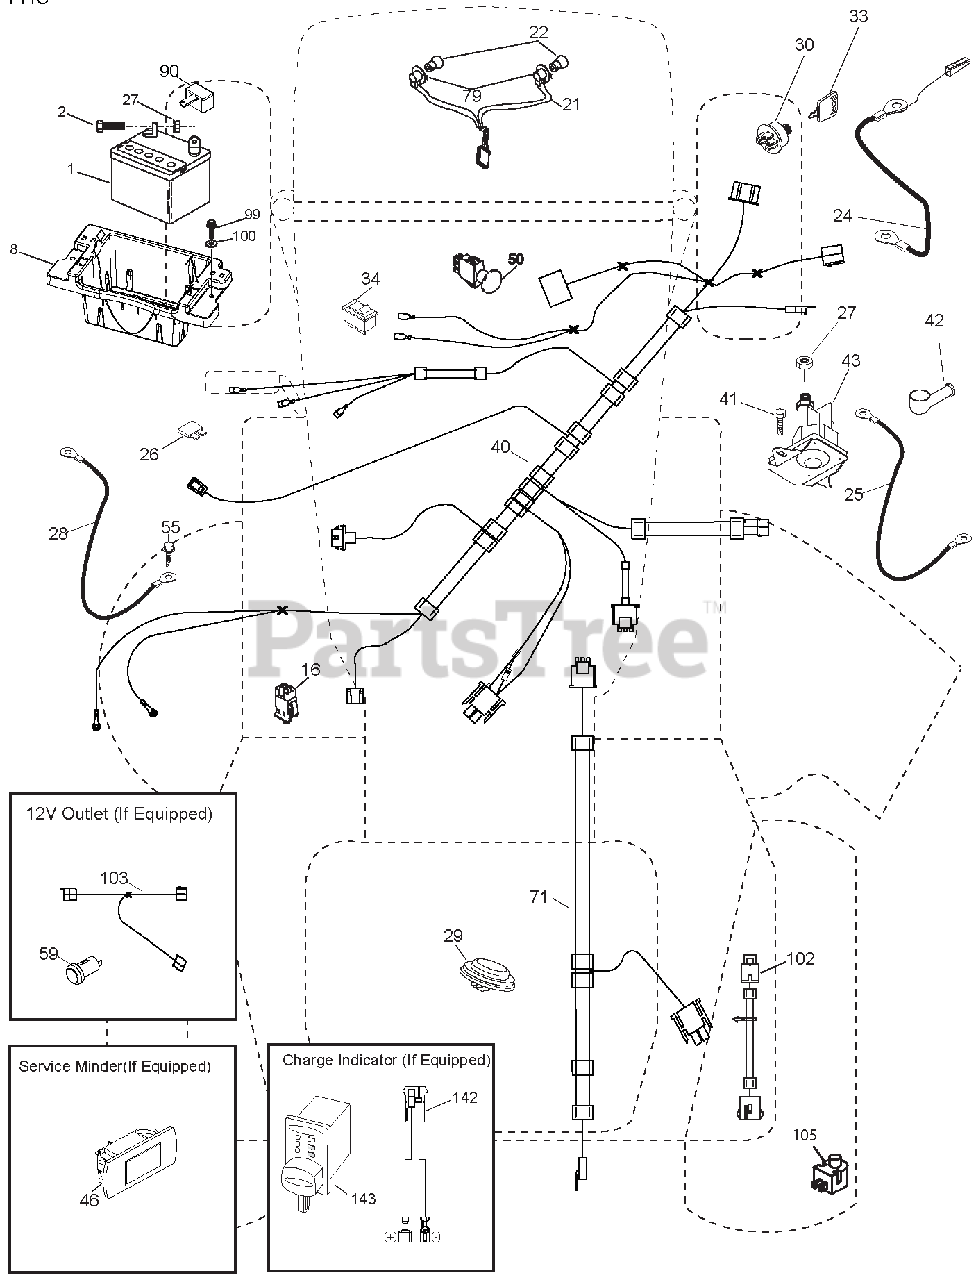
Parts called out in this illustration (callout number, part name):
1	BATTERY.12.VOLT.28.AMP.WET
2	BOLT.HEX.HD.1/4-20UNC X 3/4
8	BOX.BATTERY.MOUNT.FRONT.LT
16	SWITCH.INTERLOCK.NONO.GRAY
21	HARNESS ASM.LIGHT.22"(4152J)
22	BULB.LIGHT.#1156
24	CABLE.BTRY.PSWRE.DSH SOL.8"TEX
25	CABLE.STARTER
26	FUSE.20 AMP.
27	Nut, Keps Hex 1/4-20 unc
28	CABLE.GROUND.21"BLK.6 GA.90T
29	SWITCH.SEAT.DELTA.OPC.9LB.
30	SWITCH.IGN.DLTA.P-IN.ROS
33	KEY/CHAIN.BLISTER PACK.GEN.USA
34	SWITCH.LIGHT/RESET.B/B/RED.
40	HARNESS.IGN.DASH.HUSQ/PRED.
41	Screw 1/4-20 x 1/2
42	COVER.TERMINAL.RED
43	SOLENOID.W/BRASS PLUNGER.2005
46	HOUR METER
50	SWITCH.PTO.8 TERMINAL.BLACK
55	SCREW.5/16-18X3/4.SMGML.TAP/R
71	HARNESS.IGN.CHASSIS.TEX
79	SOCKET ASM.BULB.TWISTLOCK
90	COVER TERMINAL BATTERY FR. TEX
91	STRAP.BATTERY.MOUNT.FRONT
99	SCREW.HEXWSH.THDROL.1/4-20X3/4
100	WASHER.9/32 X 7/8 X 16GA.
102	HARNESS.PIGTAIL.K46.TEX.ROS
105	SWITCH.REVERSE.TT.PEDAL CONTRO
